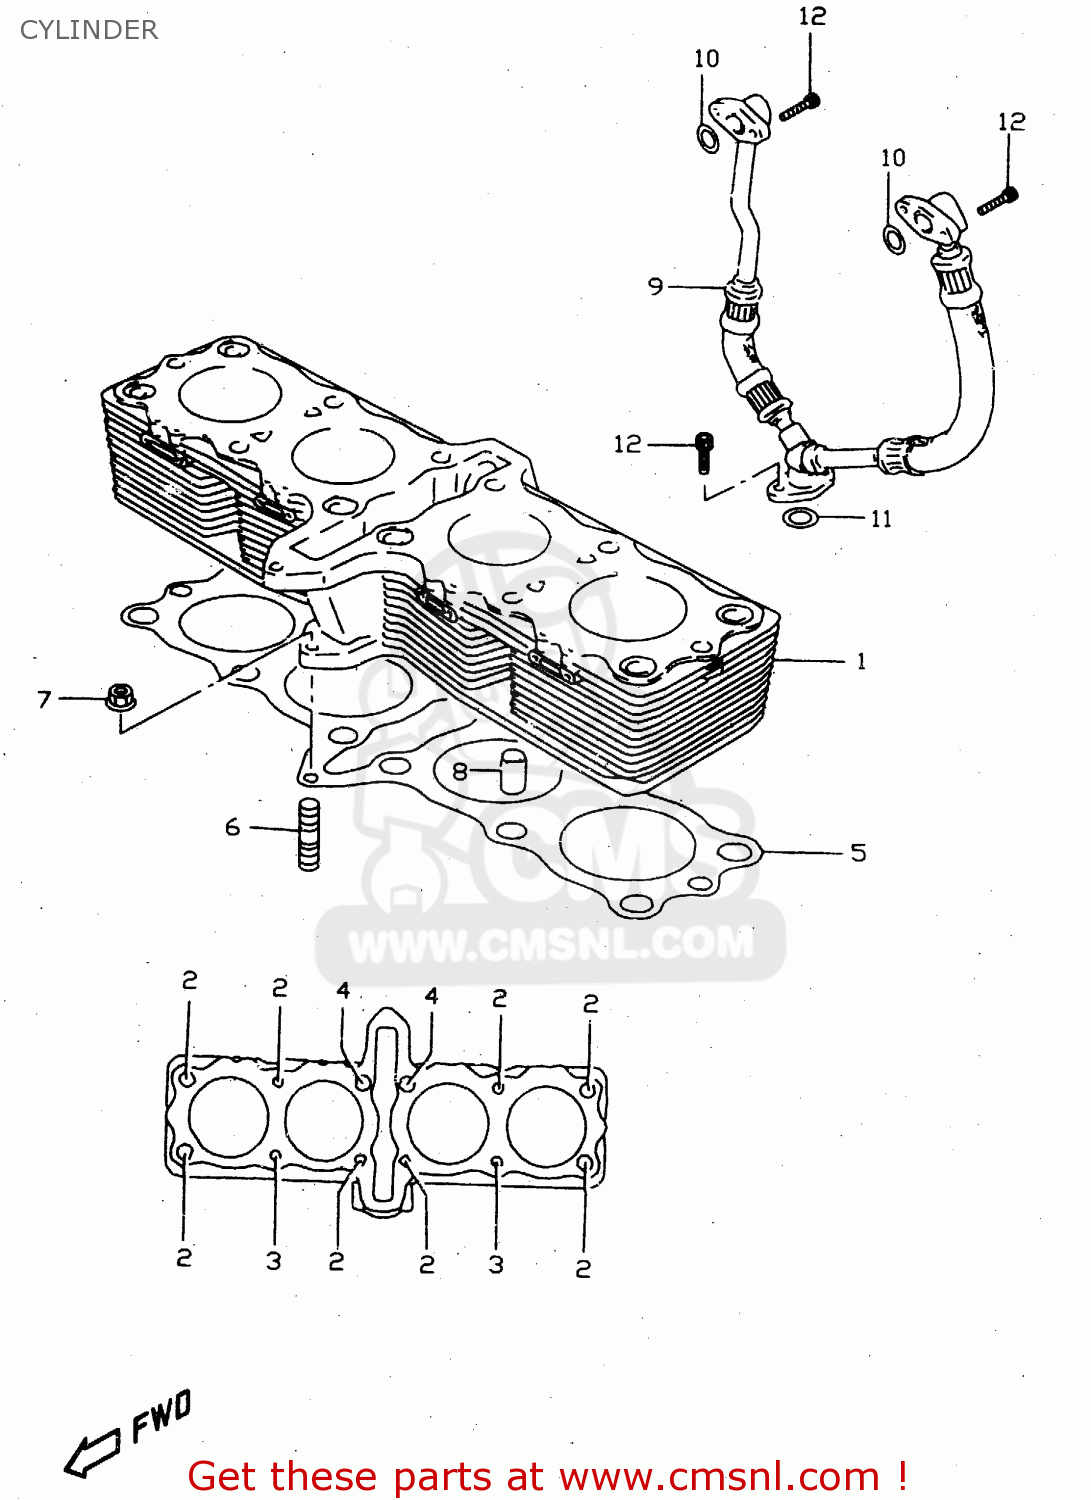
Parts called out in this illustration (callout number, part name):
1	CYLINDER
2	STUD BOLT (L:150)
3	BOLT,STUD
4	BOLT,STUD
5	GASKET,CYLINDER (NAS)
6	STUD,M6X1X32
7	NUT
8	PIN(13X10.4X20)
9	HOSE,OIL HEAD COOLER
10	O RING(D:2.5,ID:13.8)
11	O RING(D:2.4,ID:15.8)
12	BOLT,OIL FILLE
